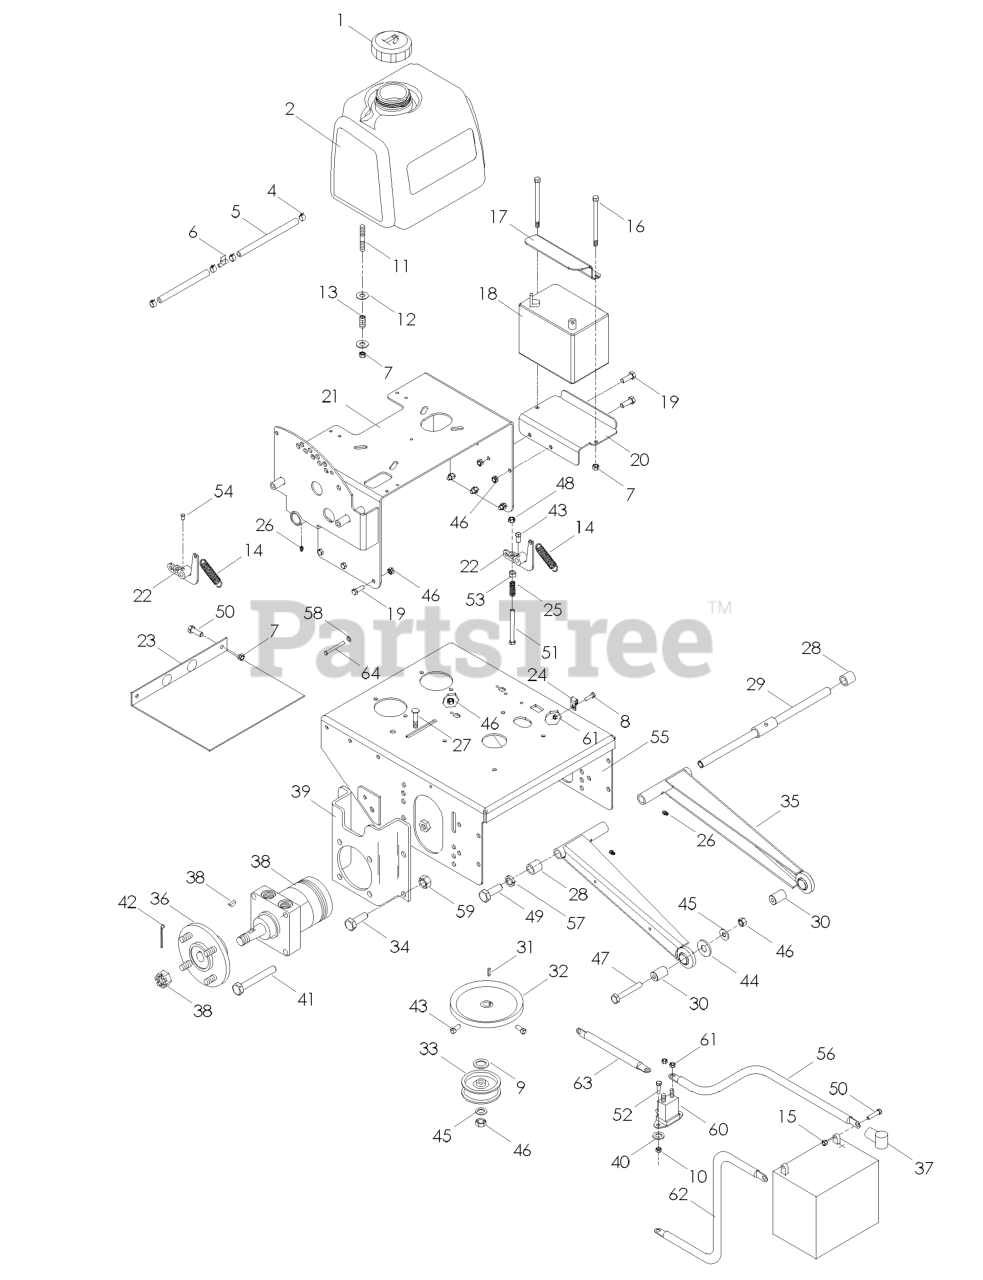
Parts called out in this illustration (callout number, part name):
1	FUEL CAP ANTI-SPLASH
3	JAM NUT 1/4C (2 2 PW01)
4	HOSE CLAMP
5	GAS LINE 10"
6	FUEL VALVE
7	NUT 5/16 NYLOC
8	HCS 1/4C X 3/4 HCS
9	WASHER, 3/8 SPEC
10	NUT 1/4C CENTER LOCK
11	STUD, 5/16C
12	WASHER 5/16 FLAT
14	SPRING-TRANS
15	NUT 5/16C CENTERLOCK
16	BOLT - 5/16 X 7
17	BATTERY STRAP
18	BATTERY, 12 V 330 AMP
19	SCREW 3/8C X 3/4 HEX CAP
20	BATTERY TRAY
21	TANK SUPPORT
22	PUMP ARM WELDMENT
23	LOWER BELT SHIELD
24	DOUBLE TUBE CLAMP
26	ZERK
27	RHSNB 3/8C X 2
29	STRUT SHAFT
30	FRONT SPACER
31	KEY 5 MM SQ X 25 MM
33	IDLER PULLEY
34	HCS 1/2C X 1 1/4 SERRATED HEAD
35	STRUT WELDMENT
36	HUB.WHEEL.ZTR
38	WHEEL MOTOR
39	MOTOR MOUNT
40	WASHER 1/4 INT TOOTH
41	HCS 1/2C X 2 3/4
42	COTTER PIN
43	SCREW 5/16C X 5/8 SQ HEAD
44	WASHER 1/2 FLAT
45	WASHER 3/8 FLAT
46	NUT 3/8C CENTERBLOCK
47	HCS 3/8C X 2 1/4
48	NUT 3/8-16 NYLOC
49	HHCS 1/2-13 X 1
50	HCS 5/16C X 3/4
51	HEX SCREW 3/8-20 X 2.75
52	HCS 1/4C X 5/8
54	5/16C X 5/8 "V" POINT
56	CABLE POSITIVE, LONG
57	WASHER 1/2" SPLIT LOCK
58	NUT PUSH
59	NUT 1/2-13 HEX NYLOC ZD
61	NUT.1/4-20.HEX.NYLOC.ZD
62	CABLE-NEGATIVE
63	CABLE POSITIVE, LONG
64	CLEVIS PIN
